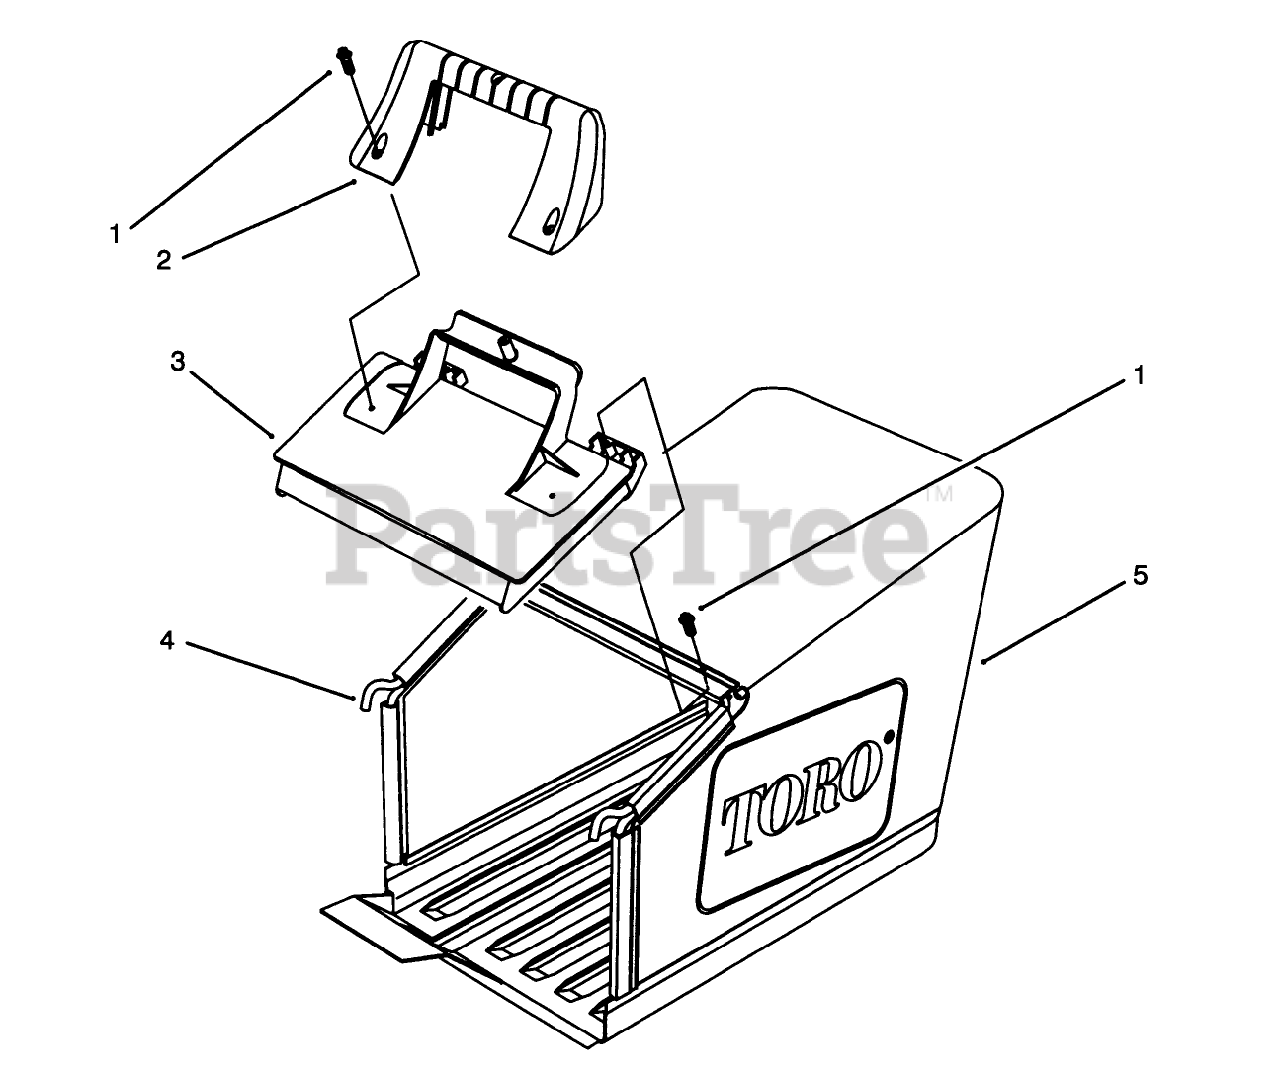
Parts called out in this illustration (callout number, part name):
1	SCREW-PPH
2	HANDLE-DOOR
3	DOOR-BAG
4	Frame
5	BAG-GRASS
